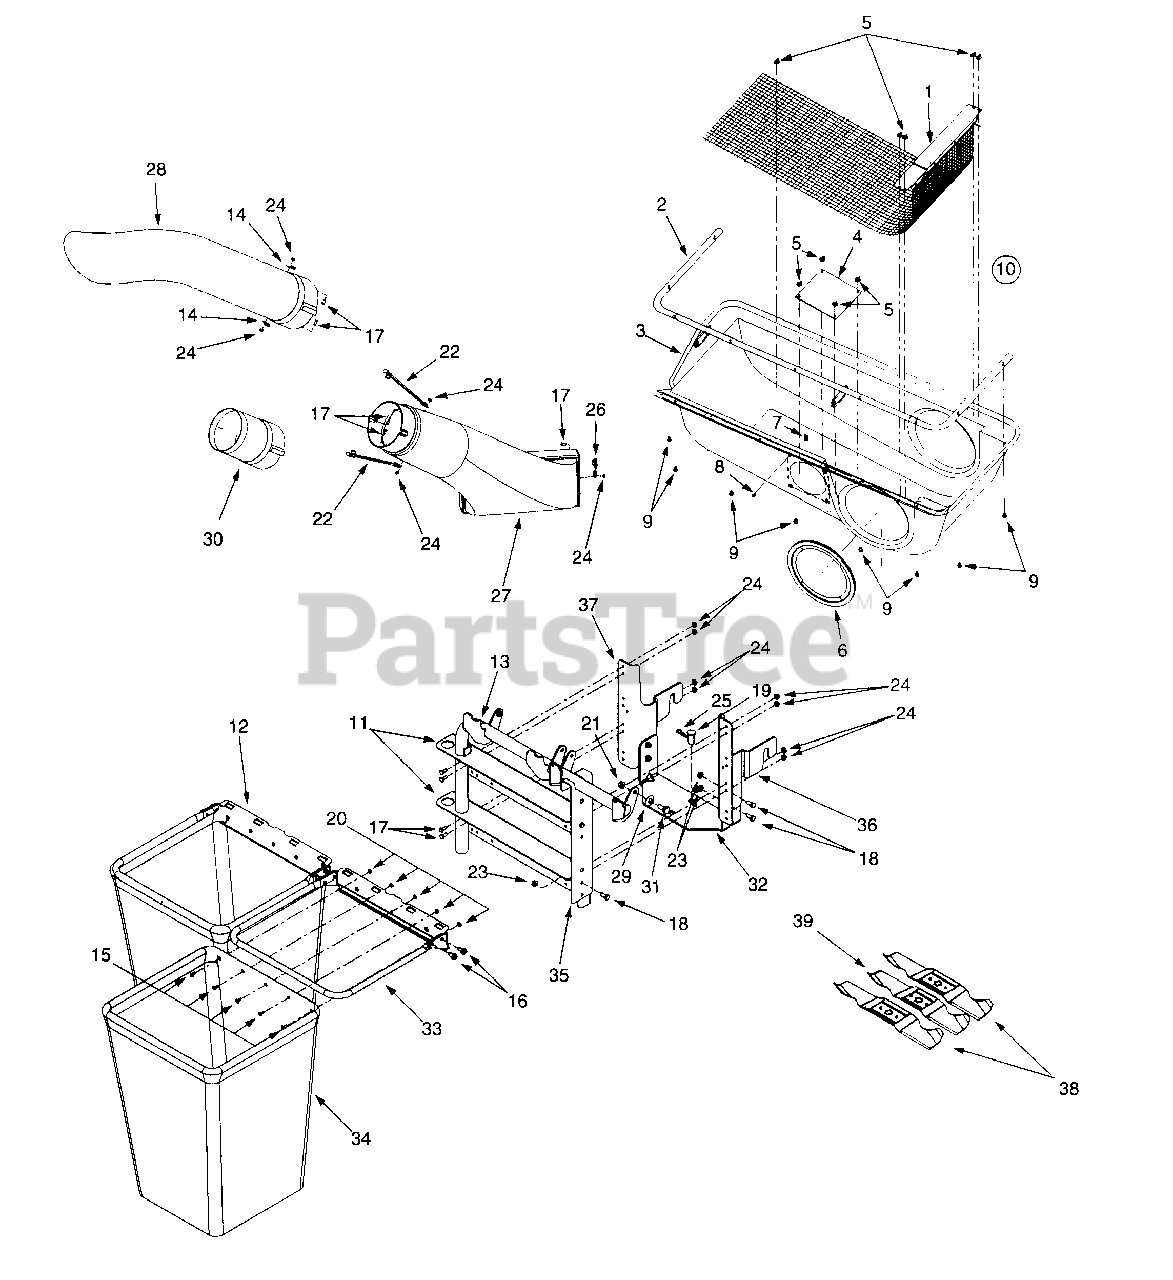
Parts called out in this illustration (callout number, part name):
3	Grass Catcher Cover
4	Plastic Plate, 1/8 x 5.6 sq.
5	Zip Twist Fastener
6	Tube Seal
7	U-Type Speed Nut, #10-24
8	Screw, #10-16 x .5
8	Screw, #10-24 x .5
9	Hex Screw, 1/4-20 x .5
9	Hex Screw, 1/4-14 x ..625
10	Cover Assembly
11	Catcher Support Tube Mounting Bracket
12	Bag Frame Hanger Bracket
13	Catcher Support Tube Assembly
14	Retainer Hook Bracket
15	Screw, #10-24 x .5
16	Self-Tapping Screw, 5/16-18 x .625
17	Hex Cap Screw, 1/4-20 x .62
18	Hex Cap Screw, 5/16-18 x .75
19	Clevis Pin
20	Hex Sems Nut, 10-24
21	Hex Flange Lock Nut, 3/8-16
22	Retainer Strap Assembly
23	Hex Flange Lock Nut, 5/16-18
24	Hex Flange Lock Nut, 1/4-20
25	Internal Cotter Pin, .148 x 3
26	Retainer Strap Assembly
27	Discharge Chute
28	Chute Tube
29	Bell Washer
30	Extension Tube
31	Shoulder Screw, .50 x .27, 3/8-16
32	Support Cross Bracket
33	Bag Frame Tube
35	Catcher Support Bracket
36	RH Catcher Support Bracket
37	LH Catcher Support Bracket
38	Star Center Blade, 16.28
39	Star Center Blade, 14.88
